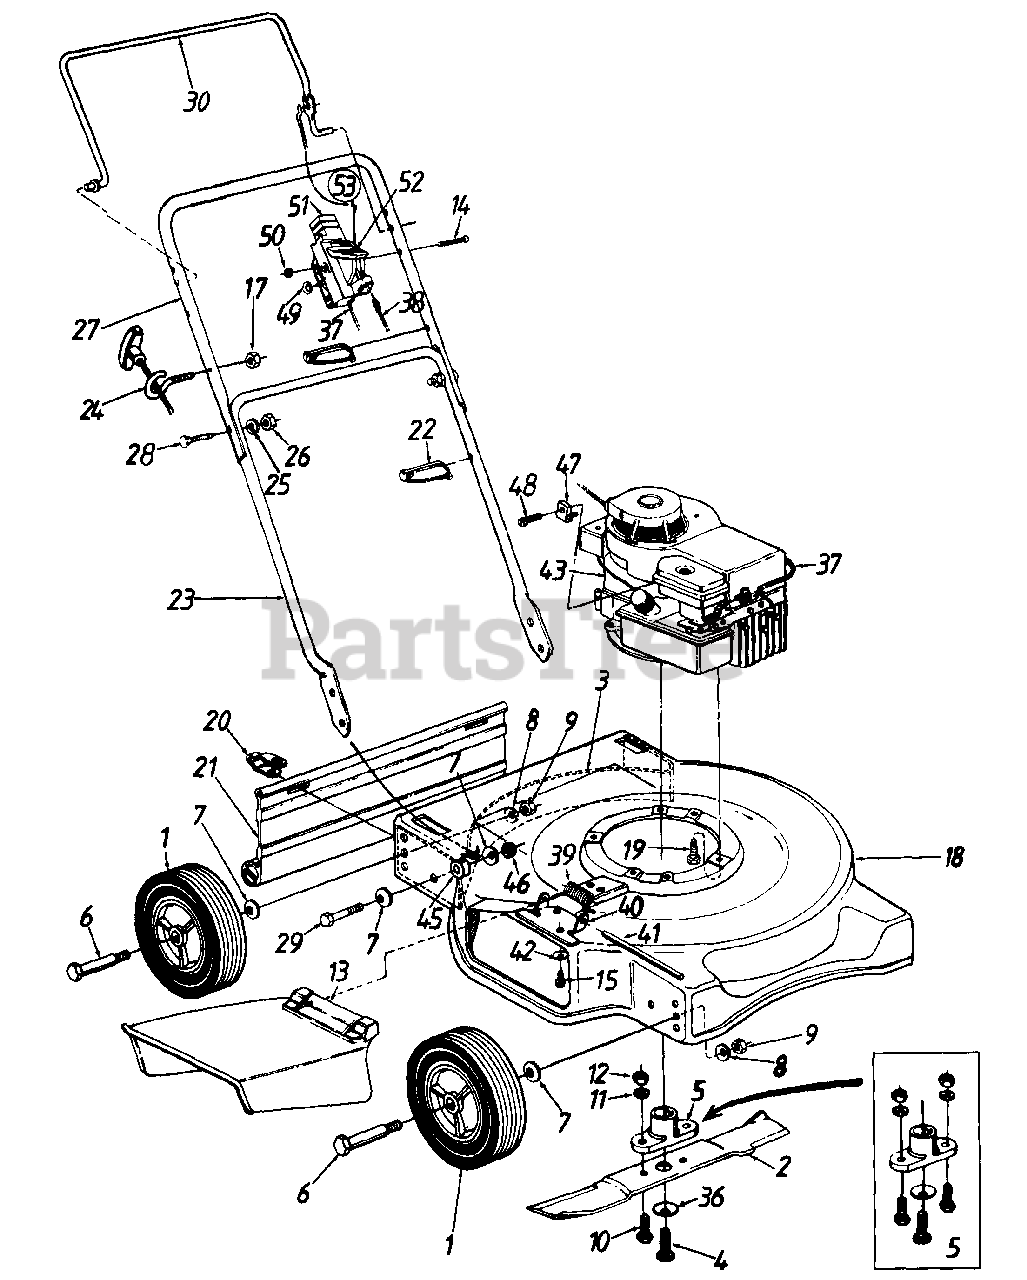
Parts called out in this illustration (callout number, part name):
1	Wheel Ass'y. Complete
2	20" Blade
5	Blade Adapter Kit (Keyed)
6	Axle Bolt
7	Bell-Wash. .380" I.D. x .88"
8	Bell-Wash. .39" I.D. x 1.13"
9	Hex Nut 3/8-16 Thd.
10	Hex Bolt 3/8-24 x 1" Lg.
11	L-Wash. 3/8" I.D.
12	Hex Nut 3/8-24 Thd.
13	Chute Deflector Ass'y.
14	Oval C-Sunk Scr.
15	Self-Tap Scr. 1/4-20 x .5" Lg.
17	Hex L-Nut 1/4-20 Thd.
20	Hinge Clip
21	Rear Flap 16.69" Lg.
22	Cable Tie
24	Rope Guide
25	L-Wash. 5/16" I.D.
26	Hex Nut 5/16-18 Thd.
29	Hex Bolt 3/8-24 x 1.5" Lg.
36	Bell-Wash..39" I.D.
37	Throttle Control Wire - 51" (B&S)
38	Control Cable - 36" (B&S)
39	Torsion Spring
40	Adapter Plate
41	Hinge Pin
42	Bell-Wash. 1/4" l.D.
43	Engine
45	Spacer
46	Hex L-Nut 3/8-24 Thd.
47	Casing Clamp (B&S)
48	Hex Wash. Hd. Scr. #10-32 x .62" Lg. (B&S)
49	Spring Wash. .66" I.D.
50	Hex L-Nut 1/4-20 Thd.
51	Throttle Body
52	Throttle Lever
53	Throttle Box Comp.
